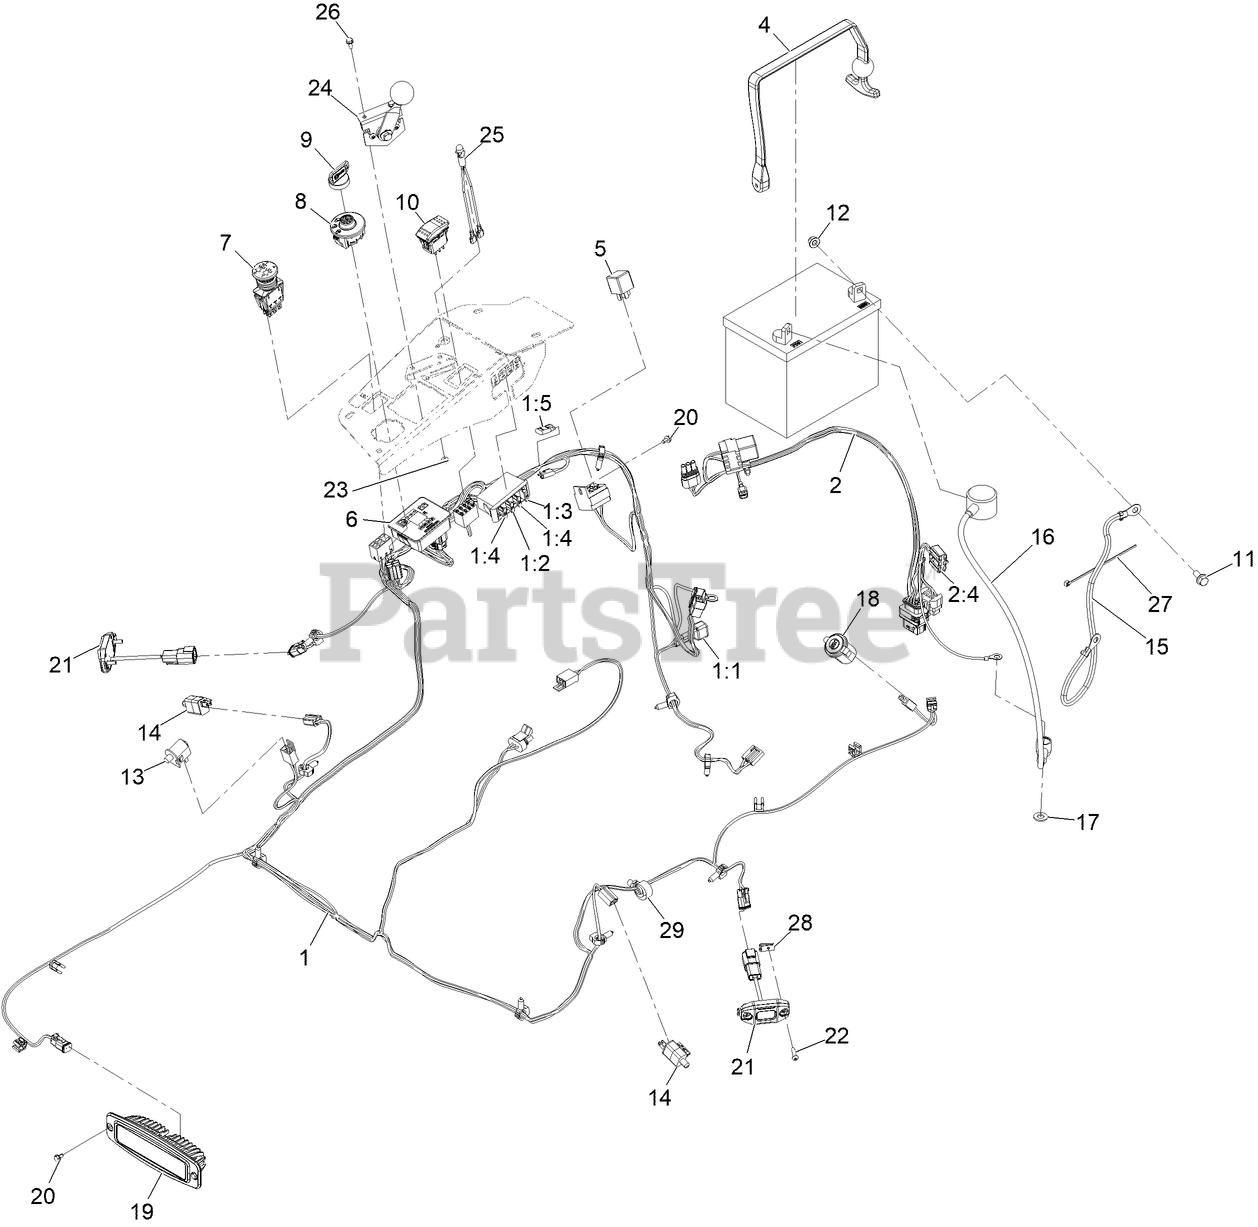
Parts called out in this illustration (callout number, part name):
1	HARNESS-MAIN LRX CARB
1:2	FUSE-BLADE, 10 AMP
1:3	FUSE-BLADE, 15 AMP
1:4	FUSE-BLADE, 25 AMP
1:5	CAP-PLUG
2	Harness-Adapter EFI, Etc
4	Strap-Bungee
6	Fuel/Hour Meter ASM
7	SWITCH, PTO 10A
8	SWITCH-IGNITION
9	KEY-IGNITION
10	SWITCH
11	SCREW-HHF
12	NUT-HF, NI
13	SWITCH-BAIL
15	CABLE-BATTERY, NEGATIVE
16	CABLE-BATTERY, POSITIVE
17	WASHER-FLAT
18	PORT-POWER, USB
19	MOUNT-FLUSH, LIGHT
20	SCREW-HWH
21	LIGHT-ROCK
22	Screw-HSBH
23	NUT-LOCK, NI
24	THROTTLE CONTROLLER-ETC
25	INDICATOR-LED, RED
26	SCREW-HWH
27	TIE-CABLE
28	Nut-Speed
29	CLIP-TIE
